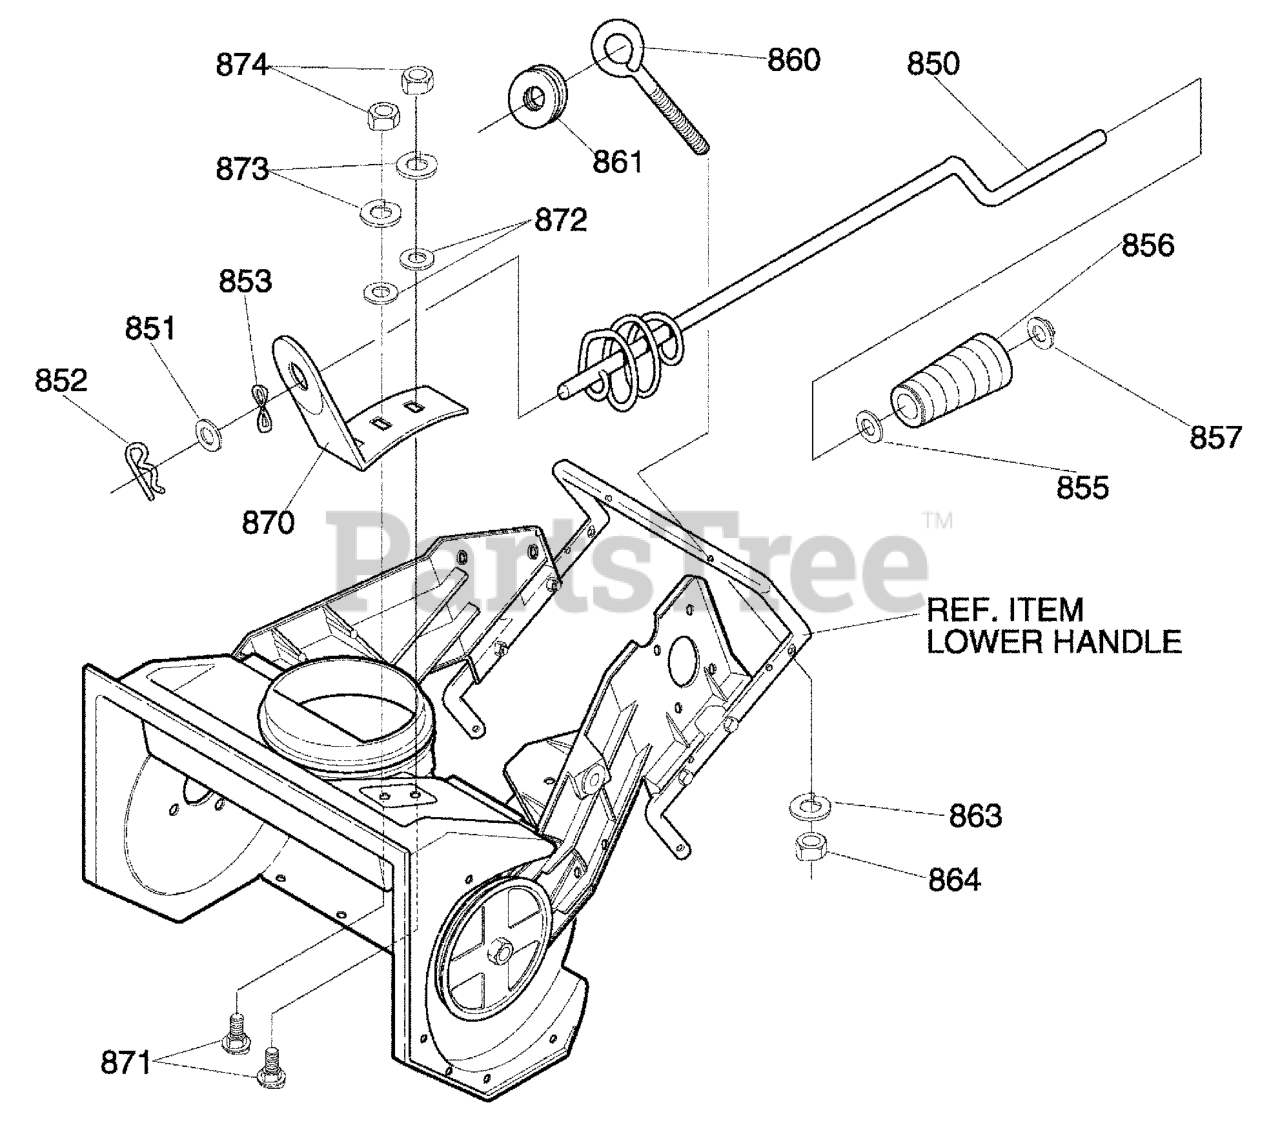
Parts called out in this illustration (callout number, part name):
850	ROD, ASSY UPPER CHUTE CONTROL
851	WASHER, FLAT .406X.81X.066
852	PIN, COTTER .094 DIAX1.00LG
853	WASHER, CURVED SPRING
855	WASHER, FLAT .406X.81X.066
856	KNOB, SLEEVE
857	NUT, PUSH
860	BOLT, EYE 3/8-16X2.00
861	GROMMET, EYE BOLT
863	WASHER, MDSPTLK
864	NUT, 3/8-16 HEXJAM
870	BRACKET, CHUTE ROTATE
871	BOLT, 5/16-18X.75 CARR.
872	WASHER, FLAT .349X.69X.066
873	WASHER, HVSPTLK .328 x .60 x .09
874	NUT, 5/16-18 REGHEX
